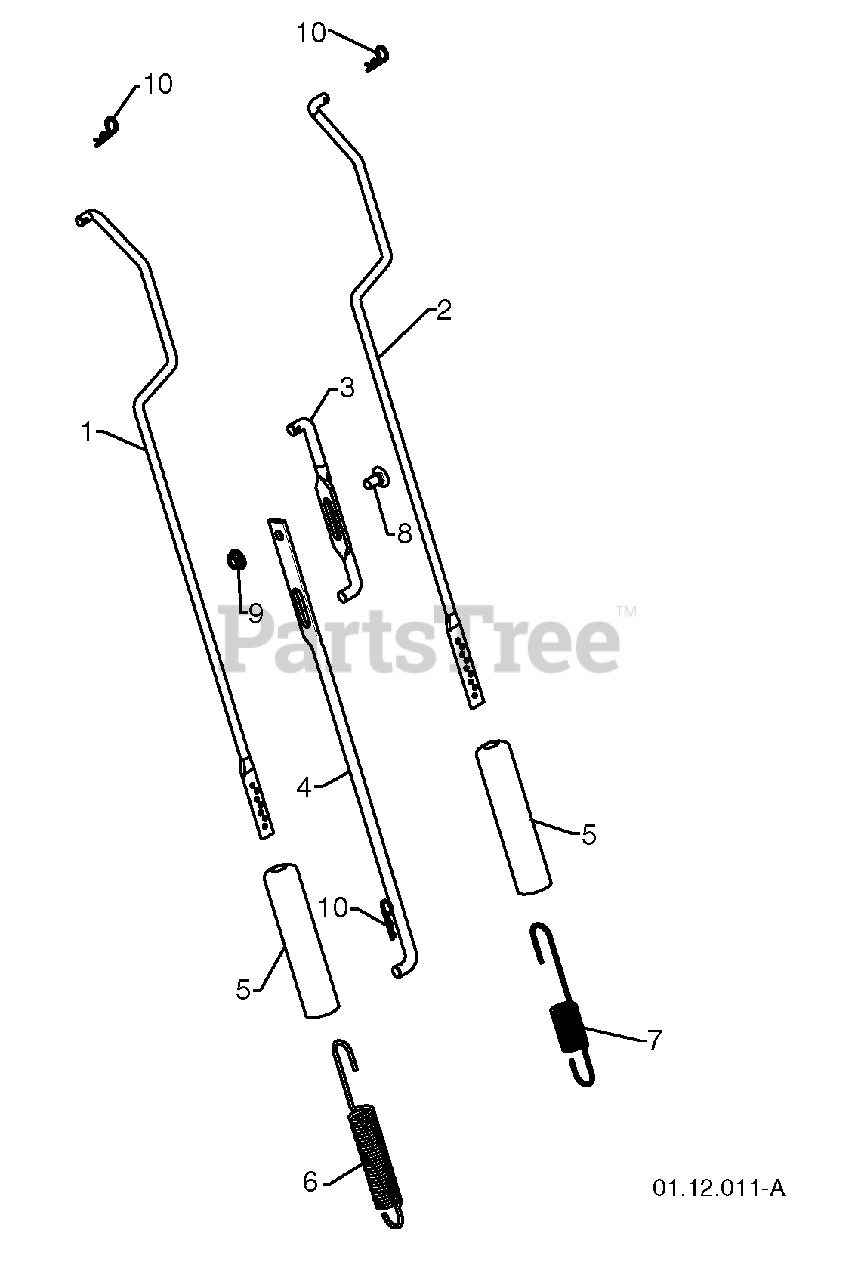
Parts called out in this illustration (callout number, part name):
1	ROD.IMPELLER
2	ROD.TRACTION
3	ROD.SHIFTER.TOP.HYD
4	ROD, LOWER, SPEED CONTROL
5	SLEEVE, SPRING
6	SPRING.CONTROL.ROD.SNOW
7	SPRING.TRACTION.ROD.SNOW
8	BOLT
9	NUT.FLANGE.5/16
10	SPRING RETAINER
